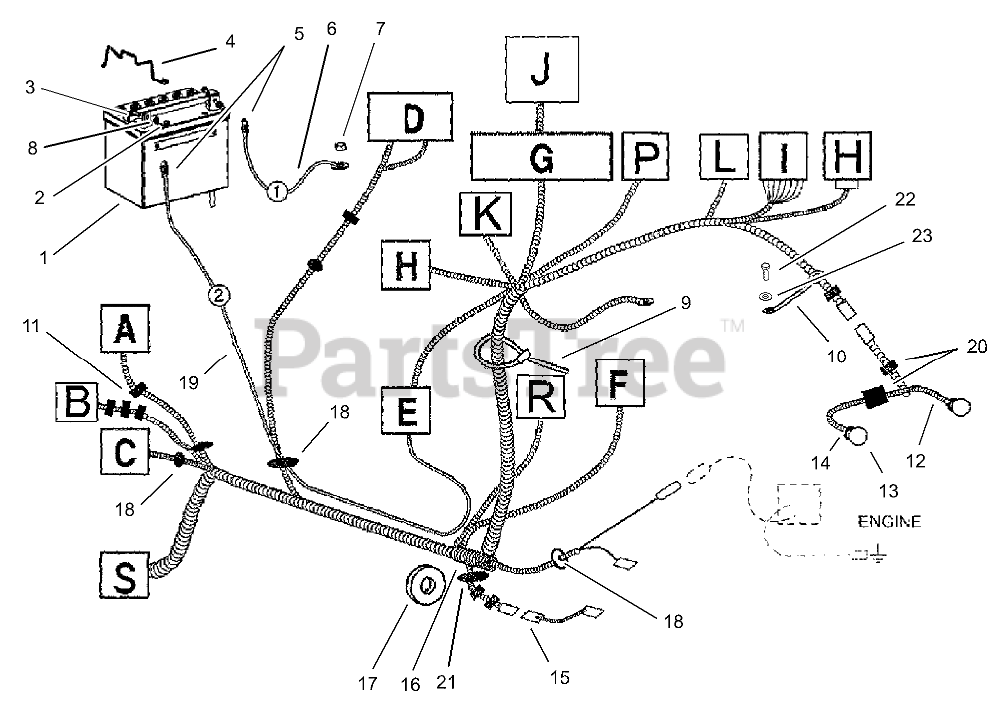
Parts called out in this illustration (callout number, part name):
1	BATTERY-12V
2	NUT-HEX
3	SCREW-HH
4	CLAMP-BATTERY
5	BOOT-RUBBER
6	CABLE-BATTERY, Negative
7	NUT-LOCK, NI
9	TIE-CABLE
10	HOLDER-HARNESS, WIRING
11	CLIP-SNAP
12	HARNESS-WIRE, LIGHTS
13	BULB-LIGHT
14	SOCKET-LIGHT
15	HARNESS-CLUTCH
16	HARNESS-WIRING
18	BUSHING
19	CABLE-BATTERY POSITIVE
20	CLIP-NYLON
21	BUSHING
22	SCREW-HH
23	WASHER-PLAIN
